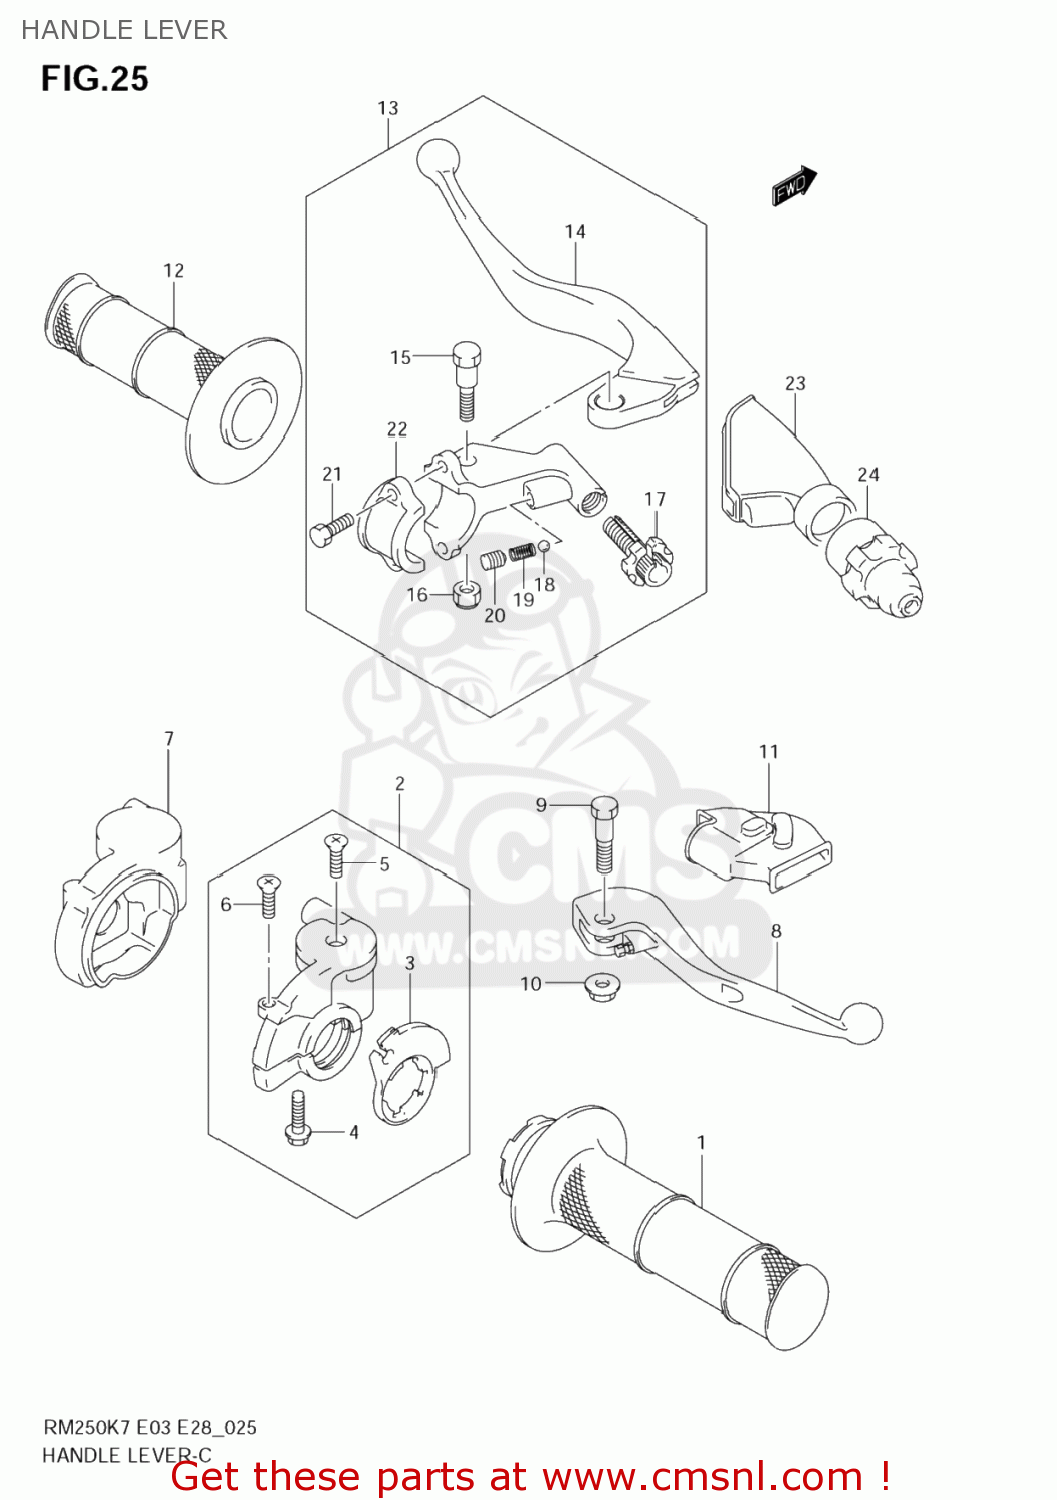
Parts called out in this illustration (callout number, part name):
1	GRIP,THROTTLE
2	CASE ASSY,THROTTLE
3	ROTOR,THROTTLE
4	BOLT
5	SCREW
6	SCREW
7	COVER,THROTTLE CASE
8	LEVER ASSY,BRAKE
9	BOLT,BRAKE LEVER
10	NUT
11	COVER,BRAKE LEVER
12	GRIP,L
13	LEVER ASSY,CLUTCH
14	LEVER,CLUTCH
15	BOLT,LEVER PIVOT
16	NUT 6MM
17	ADJUSTER,CLUTCH CABLE
18	BALL
19	SPRING
20	SCREW(6X8)
21	BOLT(6X16)
22	HOLDER
23	COVER,CLUTCH LEVER
24	COVER,CLUTCH ADJUSTER
